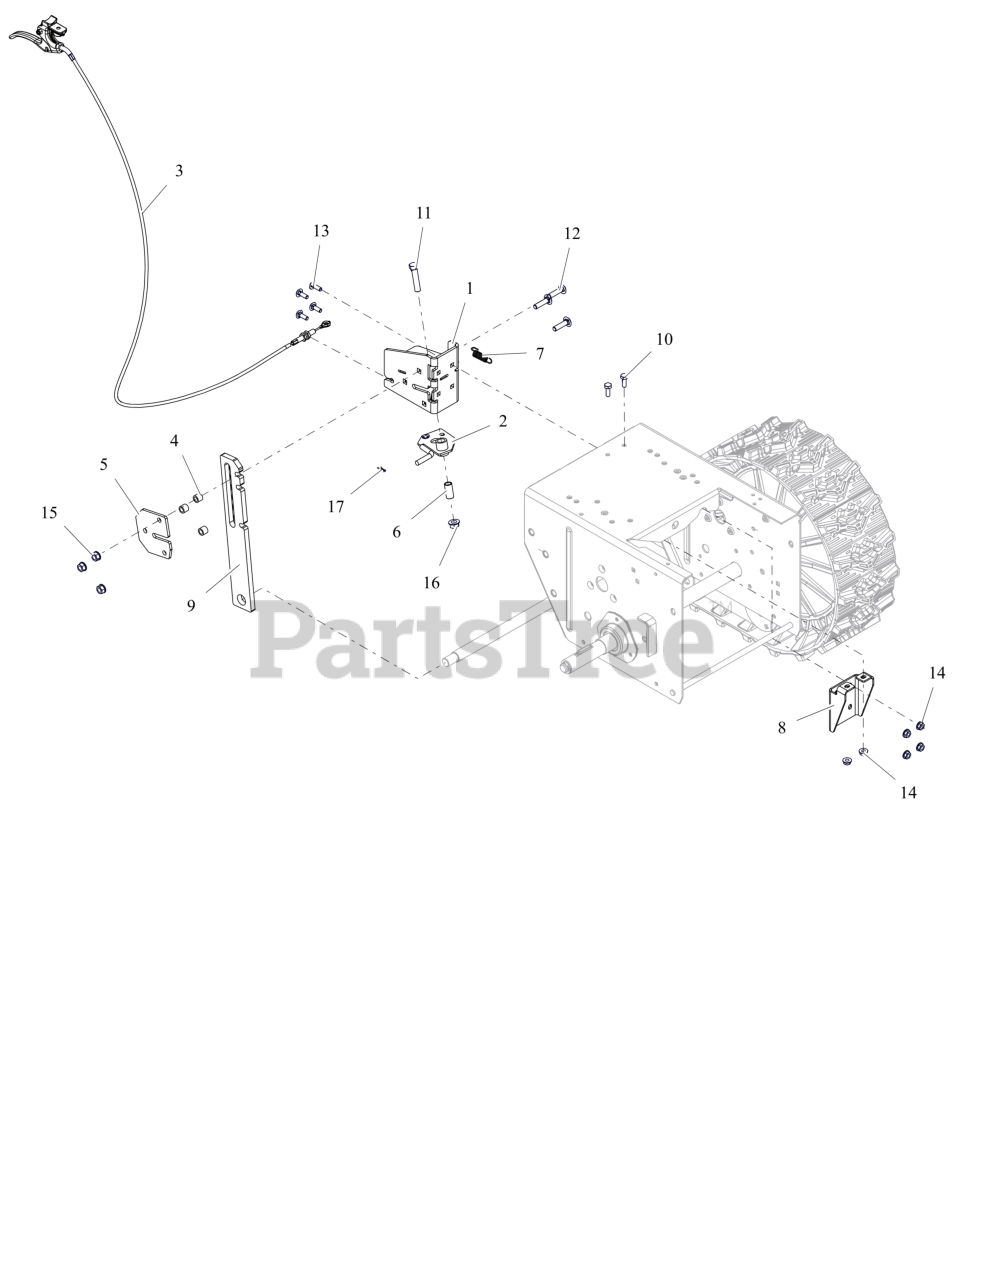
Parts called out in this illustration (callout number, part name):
1	BRACKET,HEIGHT ADJUSTER-DELUXE
2	LOCK,HEIGHT ADJUSTER TRIGGER
3	CABLE, TRACK REMOTE
4	SPACER .50 X .32 X .42
5	PLATE, HEIGHT ADJUSTER
6	BSHG-SLV .385X.500X1.045
7	SPRING-EXT .047 X .438 X 1.85
8	BRACKET, REINFORCEMENT
9	ADJUSTER, HEIGHT-BWT
10	BLT, HEX .25-20X.75 G5 ZCC
11	BLT, HEX .38-16X1.75 G5 ZCC
12	BLT, RHSSN.31-18X1.25 G5 ZCC
13	BLT, RHSN .25-20X.750 G5 ZCC
14	NUT-LK-CTR-FLG .25-20 ZC120
15	NUT-LK-TOP-FLG .312-18 GF ZCC
16	NUT-LK-CTR-FLG .375-16 GF ZCC
17	PIN, HAIR #178 .06X.77 ZCC
